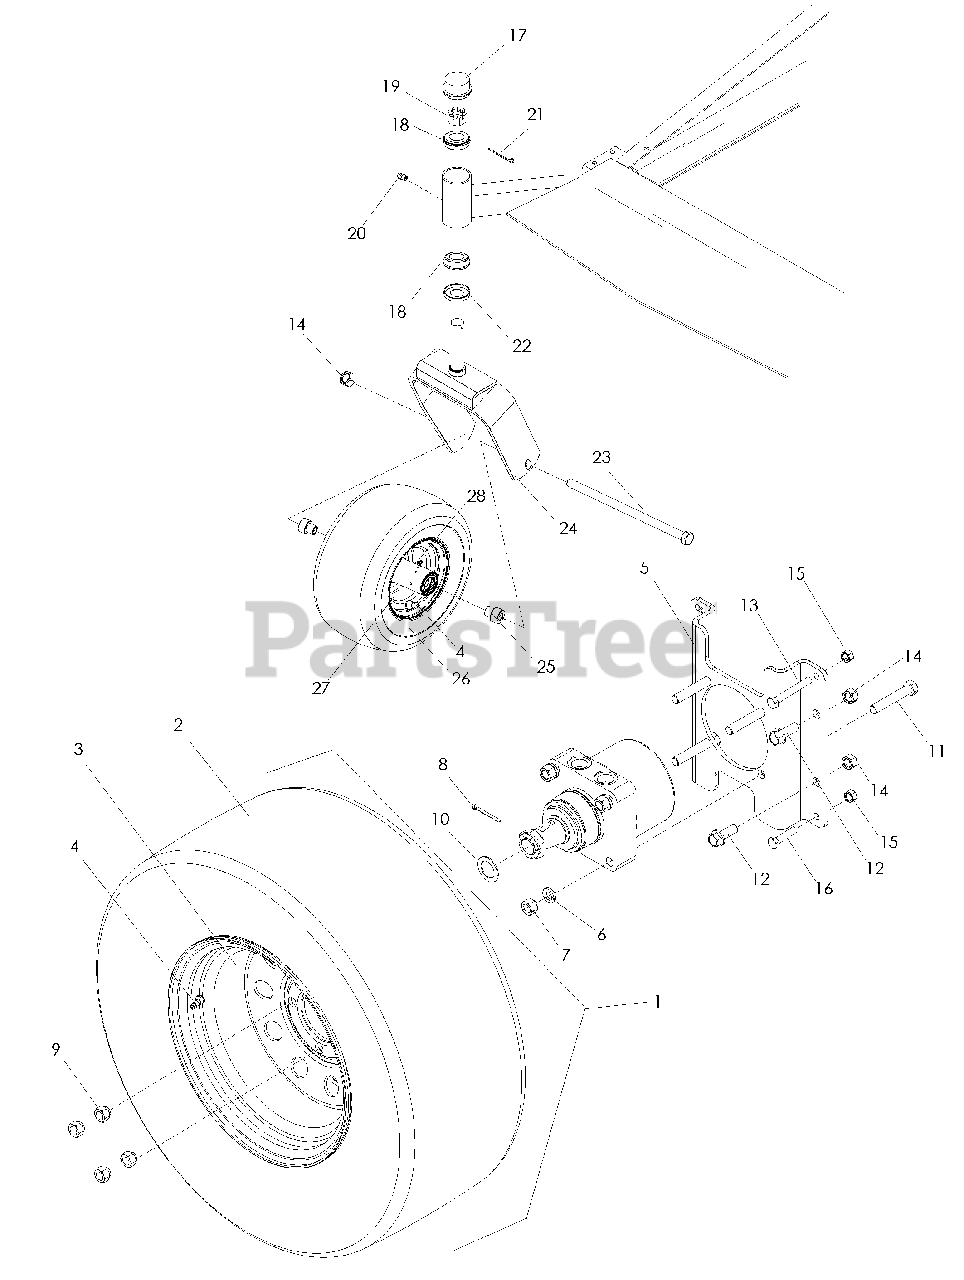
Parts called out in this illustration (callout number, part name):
1	Tire Assem, Rr 23 x 9.5-12
5	Mount Wheel Motor
6	Washer 1/2 Splt Lock
7	Nut 1/2-13 Hex
8	Pin, Cotter
9	Lug Nut 1/2
10	Bushing, 1 x 14 Ga
11	Hcs 1/2-13 x 2 3/4
12	Bolt 1/2-13 x 1 1/4 Whizlk
13	Hcs 3/8-16 x 2 1/4
14	Nut 1/2-13 Hex Nyloc
15	Nut 3/8-16 Hex Nyloc
16	Hcs 3/8-16 x 1 1/4
17	Cap, Grease
18	Bearing, Roller
19	Nut 1-14 Slotted Jam
21	Pin, Cotter
23	Hcs 1/2-13 x 9 1/2
24	Yoke, Caster
25	Spacer, Axle
26	Wheel Assem, Caster
28	Zerk
